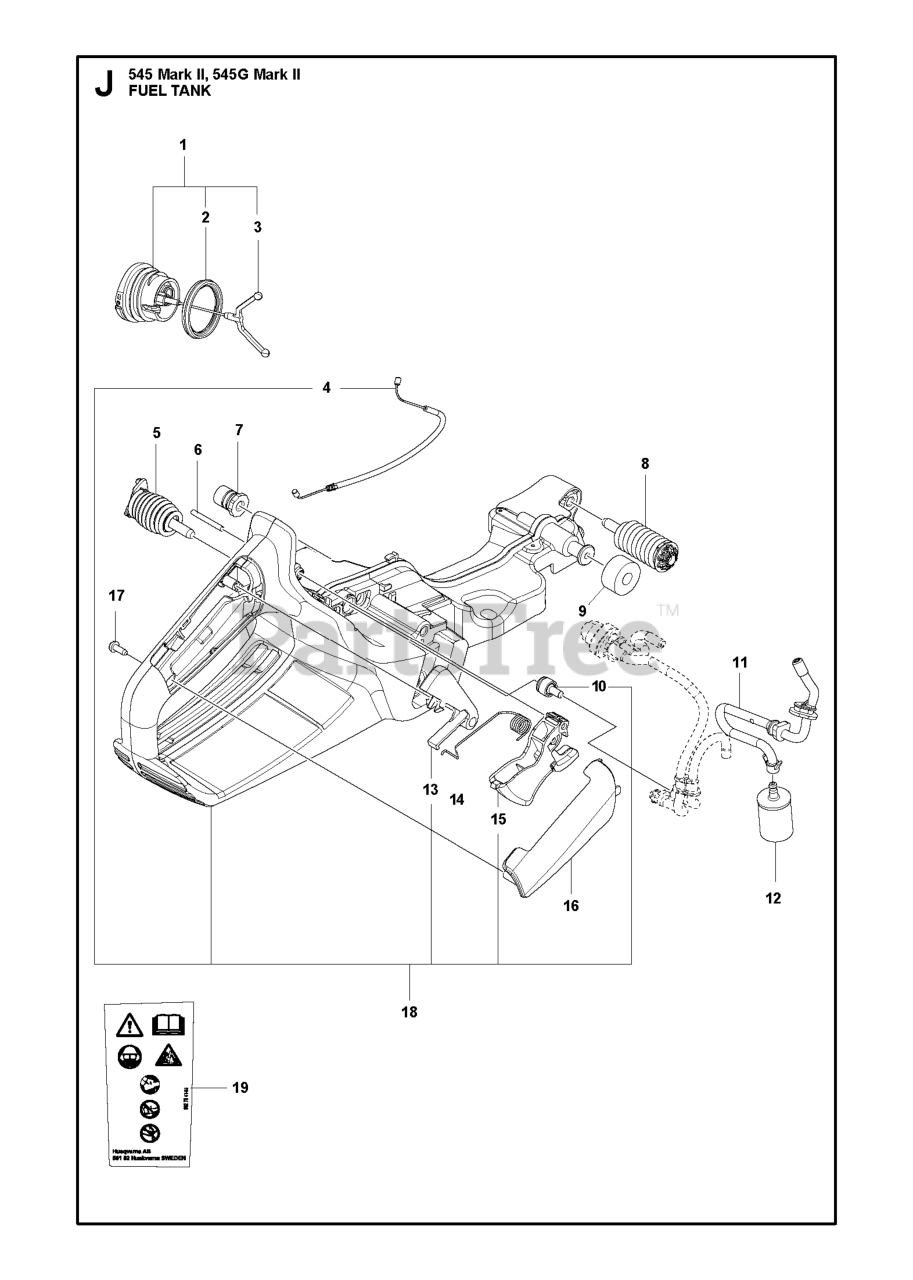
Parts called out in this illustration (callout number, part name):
1	TANK CAP ASSY
4	THROTTLE CABLE ASSY 545/550 M
5	ANTIVIBRATION ELEMENT REAR
7	LATERAL SUPPORT
8	ANTIVIBRATION ELEMENT FRONT
9	DEFLECTION LIMITER
10	FUEL TANK VENT
11	FUEL HOSE
12	FUEL FILTER
13	THROTTLE LOCKOUT
16	HANDLE INSERT
17	SCREW CITXPANT
18	Fuel Tanks
